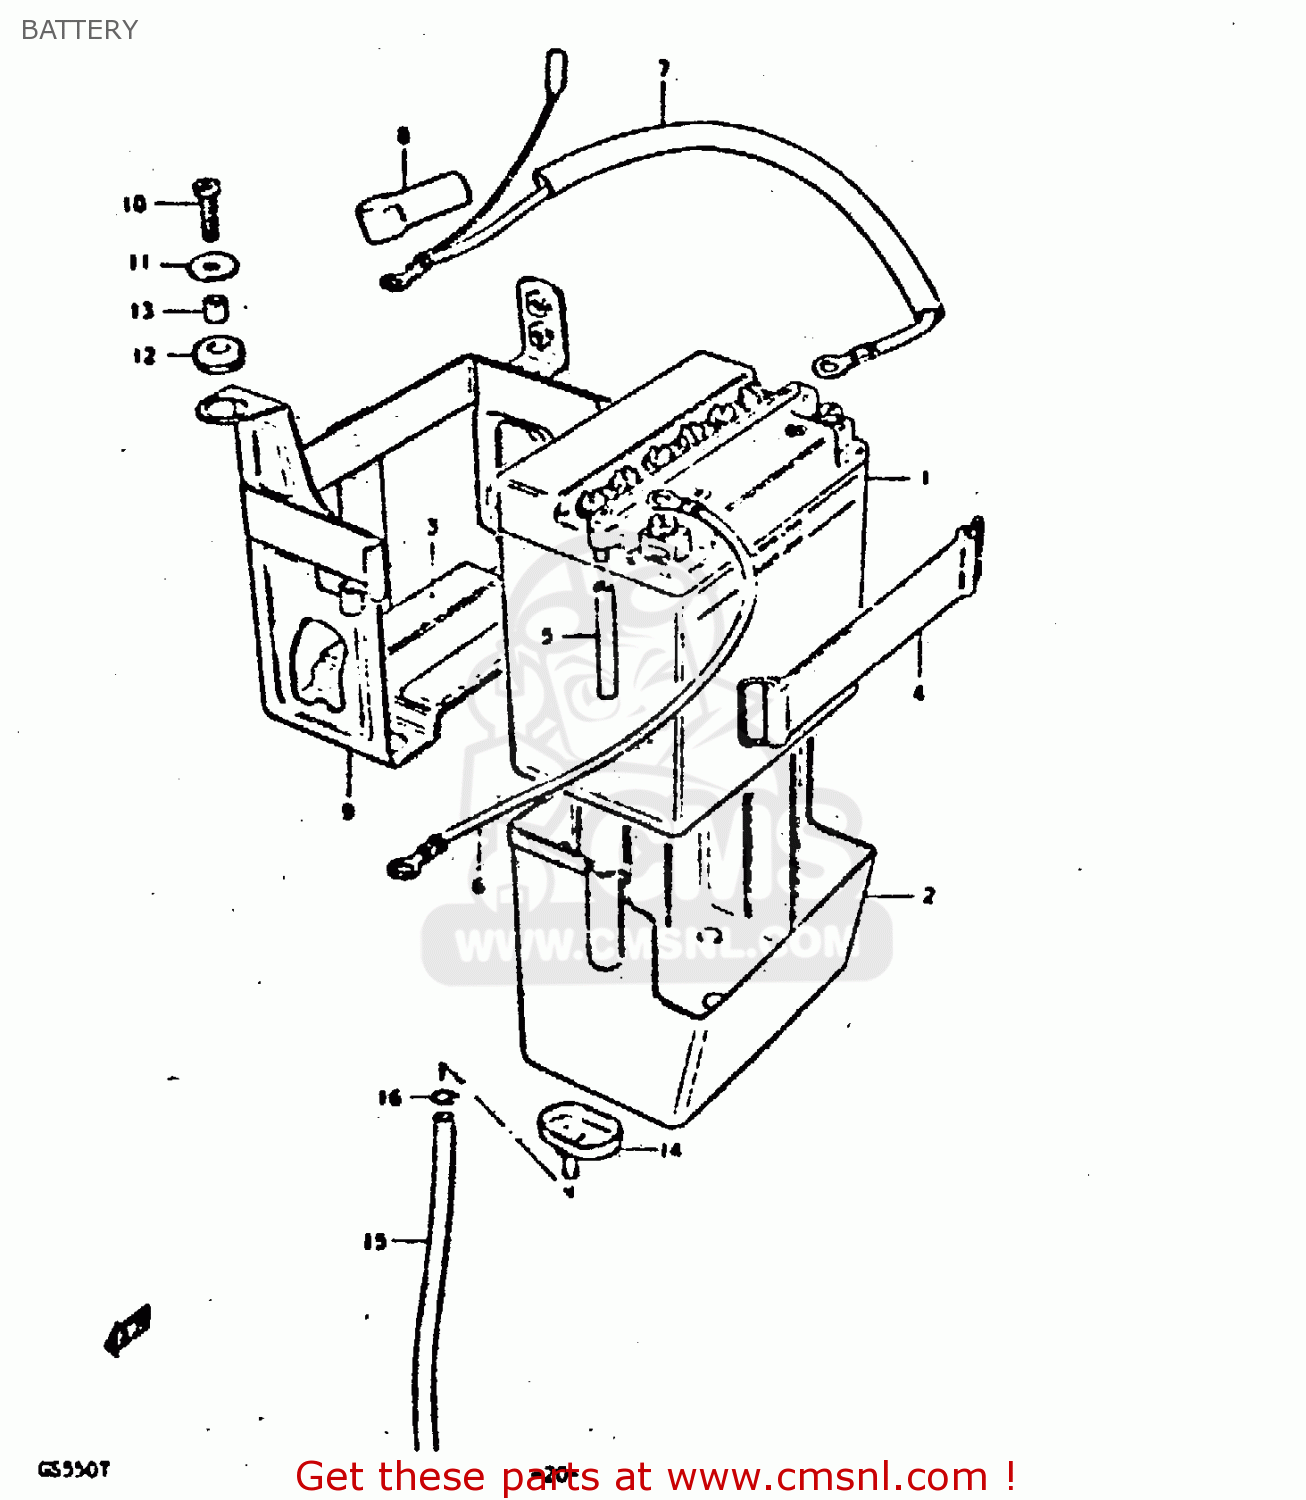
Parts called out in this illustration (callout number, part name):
1	BATTERY ASSY (12V)
2	CASE,BATTERY
3	PROTECTOR,20X9
4	BAND
5	HOSE, EXHAUST (L:45)
6	WIRE,STARTER MOTOR LEAD
7	WIRE,BATTERY PLUS
8	CAP,TERMINAL
9	HOLDER,BATTERY
10	BOLT(6X20)
11	WASHER
12	CUSHION
13	SPACER(6.1X9X7.5)
14	FUNNEL,BATTERY EXHAUST
15	HOSE,BATTERY EXHAUST
16	CLIP
